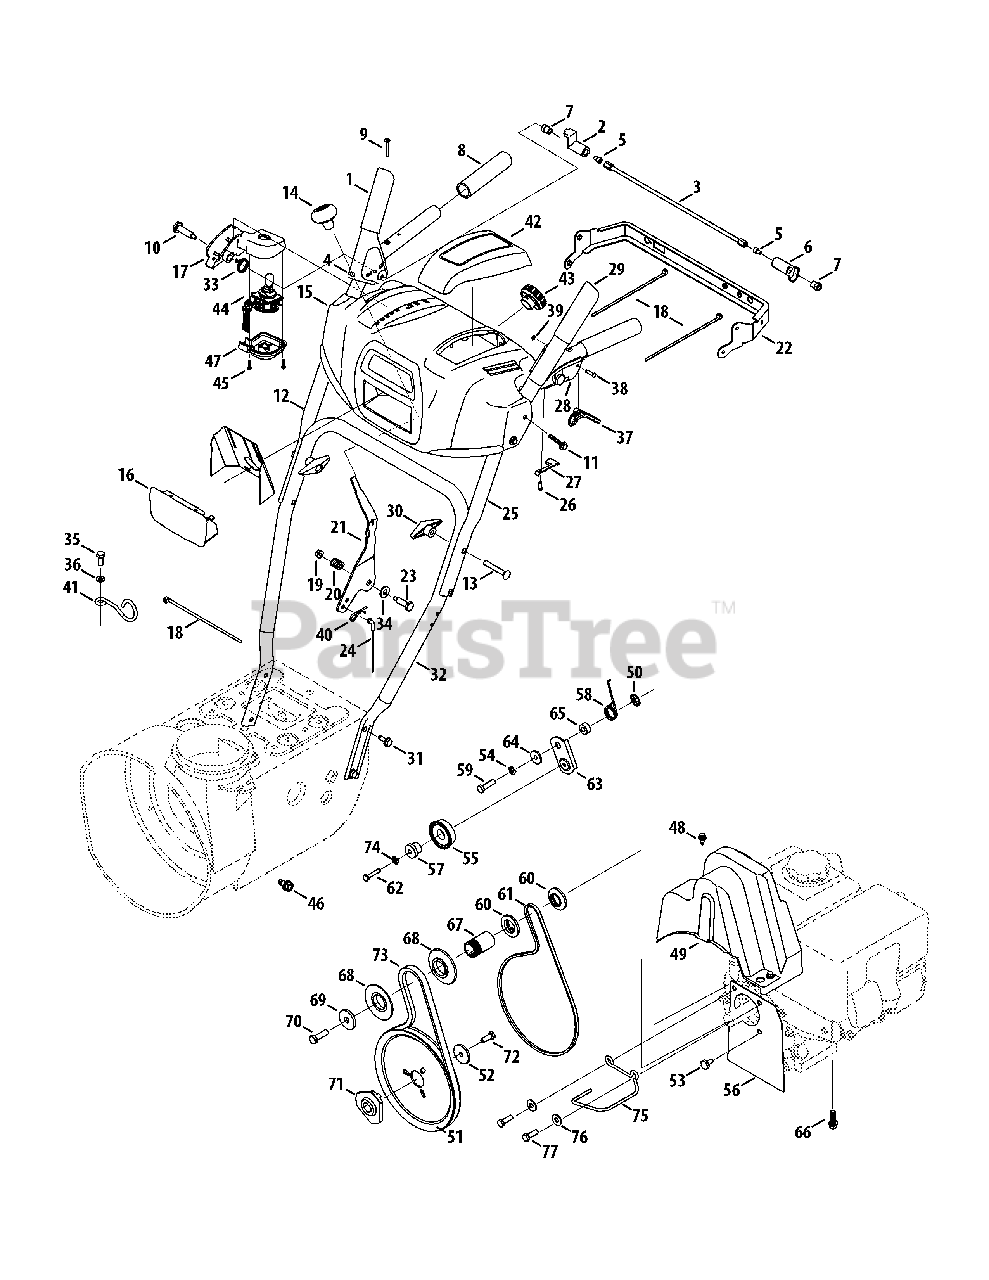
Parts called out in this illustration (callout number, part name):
1	Handle Engagement Ass’y RH
2	Lock Plate
3	Pivot Rod
4	Rubber Bumper
5	Screw, 1/4-20 x .500
6	Clutch Lock Cam
7	Shoulder Nut, 1/4-20
9	Screw, #10-24 x 0.375
10	Shoulder Screw, 1/4-20
11	Screw, 1/4-20 x 1.625
12	Upper Handle RH
13	Carriage Screw, 5/16-18 x 2.25
14	Shift Knob
15	Handle Panel
17	Handle Clutch Lock Assembly - RH
18	Cable Tie
19	Flange Lock Nut, 1/4-20
20	Compression Spring
21	Shift Lever
22	Panel Bracket
23	Shoulder Screw
24	Speed Selector Cable
25	Upper Handle LH
26	Screw, #8-16 x 0.50
27	Clutch Lock Spring
28	Handle Clutch Lock Assembly - LH
29	Handle Engagement Assembly LH
30	Wing Knob
31	Screw, 5/16-18 x 0.75
32	Lower Handle
33	Torsion Spring
34	Flat Washer
35	Screw, M8-1.25
36	Flat Washer, .330 x .630 x .0635
37	Steering Control
38	Pin, 3/16
39	E-Ring
40	Click Pin
41	Cable Guide
42	Handle Panel Cover
43	LED Light Socket
44	Electric Chute Harness
45	Screw, .159 OD x .610
46	Screw (For ground wire)
47	Joystick Housing Cover
48	AB Screw, 1/4-20 x 0.625
49	Belt Cover
50	Push-on Nut
51	Auger Pulley
52	Flat Washer
53	Shoulder Screw
54	Lock Washer
55	Idler Pulley Assembly
56	Plt., Cvr.
57	Spacer
58	Torsion Spring
59	Hex Screw, 5/16-24 x 1.25
60	Pulley Half
61	Belt, Wheel Drive
62	TT Screw, 1/4-20 x 1.25
63	Drive Clutch Idler Bracket
64	Shoulder Spacer
66	TT Sems Screw, 3/8-16 x 1.0
67	Spacer
68	Pulley Half
69	Flat Washer
70	Hex Bolt, 3/8-24 x 1.25
71	Pulley Adapter
72	Hex Bolt, 5/16-24 x 0.875
73	V-Belt,.500 x 35.00 Lg
74	Lock Washer
75	Belt Guide
76	Flat Washer, .349 x .879 x .063
77	Screw, 5/16-24 x 1.00
